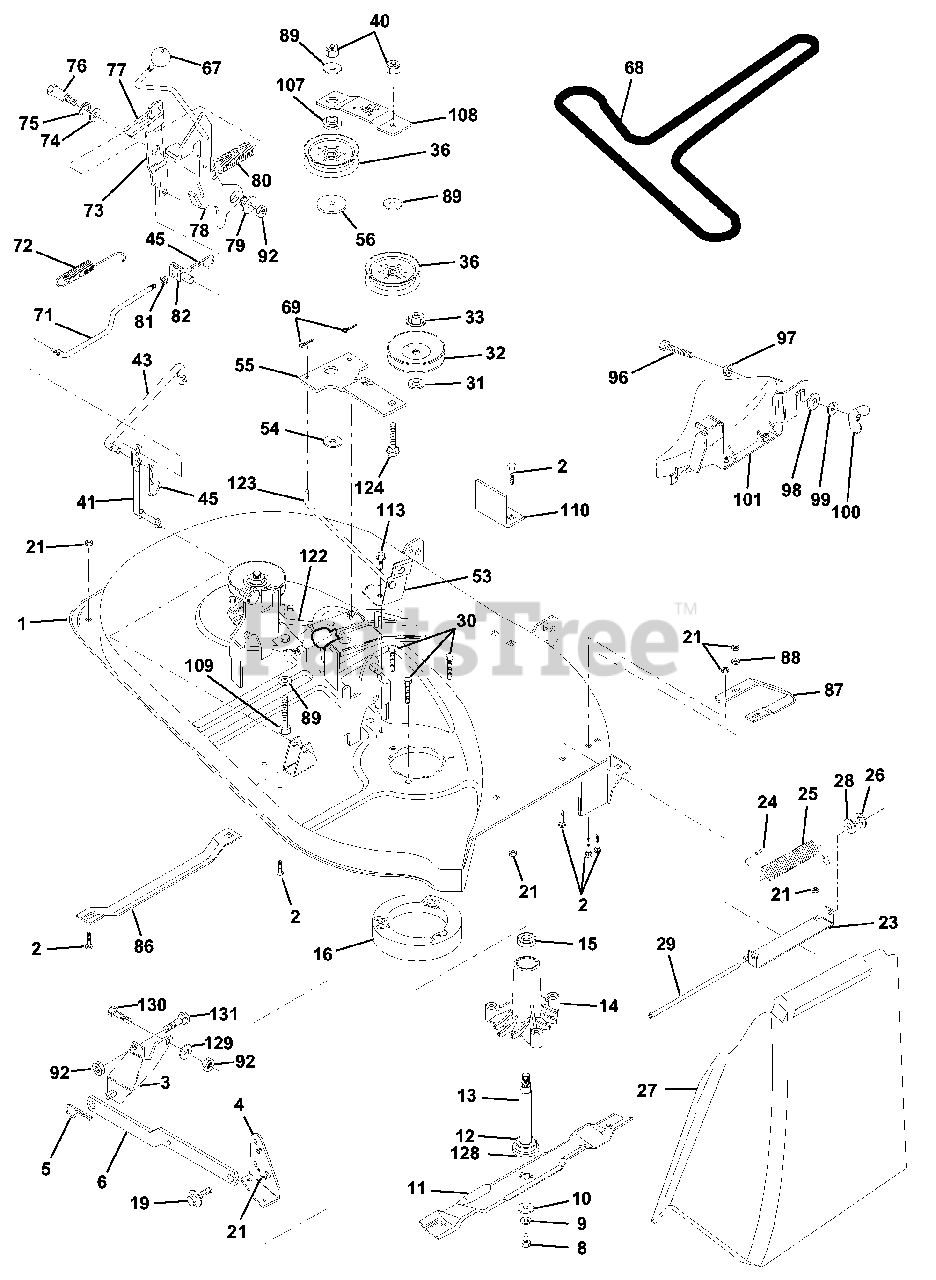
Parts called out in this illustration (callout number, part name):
1	Asm Mower Housing
2	Bolt Rdhd Sqnk 5/16-18unc X 3/4
3	Bracket Asm Fr Sway Bar 38/42
4	Bracket Asm Deck Sway Bar
5	Retainer Spring
6	Arm Suspension Rear
8	Bolt 3/8 - 24 X 1.25 Gr 8
9	Washer Lock Hvy 3/8
10	Washer Hard Blade Mower Vented
11	Blade Mower Mulching 38"
12	Bearing Ball #6024 (Mandrel)
13	Shaft Asm W/lower Bearing
14	Housing Mandrel Vented
15	Bearing Ball Mandrel
16	Stripper Mower Vented
19	Bolt Shoulder
21	Nut Crownlock 5/16-18 UNC
23	Bracket Deflector Mower
24	Cap Sleeve 80x 112 Blk Mower
25	Spring Torsion Deflector 2 52
26	Nut Push Phos & Oil
27	Shield Deflector
28	Washer 11/32 X 5/8 X 16 Ga
30	Screw Thdrol Hex Head Zinc Mwr
31	Washer Spacer Mower Vented
32	Pulley Mandrel
33	Nut 9/16 Toplock Flng Oil Dip
36	Pulley Idler Flat 3 060
40	Nut Crownlock 3/8-16 UNC
41	Rod Pivot W/nibs
43	Rod Clutch Secondary
45	Spring Retainer 1" Zinc/cad
54	Washer Hardened
56	Spacer Retainer Pm Mower
67	Knob Rd 1/2-13 Plstc Thds Blk
68	V-Belt Mower
69	Pin, Cotter 3/32 x 3/4
71	Rod Clutch Primary 38/42
72	Spring Return
73	Arm Clutch Secondary
74	Washer 25/32 X 1-5/8 X 16 Ga
75	Ring Klip #t5304-75
76	Bolt Shoulder 3/8-16 Unc 1 44
77	Keeper Spring 4 000
78	Arm Asm Clutch Primary
79	Bushing 747 Od X 794 Lg Brass
80	Spring Clutch Mower
81	Nut Hex Jam 3/8-16
82	Trunnion Adj 94
86	Runner, LH
87	Runner, RH
88	Washer 11/32 x 3/4 x 16 Ga.
89	Washer 13/32 x 1 x 12 Ga.
92	Nut Lock Hex W/Ins 3/8-16 Unc
96	Bolt 3/8-16 x 1-1/4 Mulcher
97	Nut Crownlock 3/8-16 UNC
98	Washer 13/32 x 1-1/4 x 16 Ga.
99	Washer Lock Hvy Hlcl Spr 3/8
101	Cover Asm Mulching 38"
107	Spacer, Retainer
108	Stiffener, Idler Arm
109	Bolt, Hex Head 3/8-16 x 2-1/2
110	Upstop Deck Front 38"
113	Screw Thdrol 5/16-18 X 3/4
122	Rod, Brake, LH
123	Rod, Brake, RH
124	Bolt, Carriage 3/8-16 x 1-3/4
128	Washer Felt
129	Washer 13/32 x 13/16 x 12 Ga.
130	Bolt, Fin Hex 3/8-16 UNC x 1 Gr. 5
131	Bolt, Rdhd Sqnk 3/8-16 x 1
